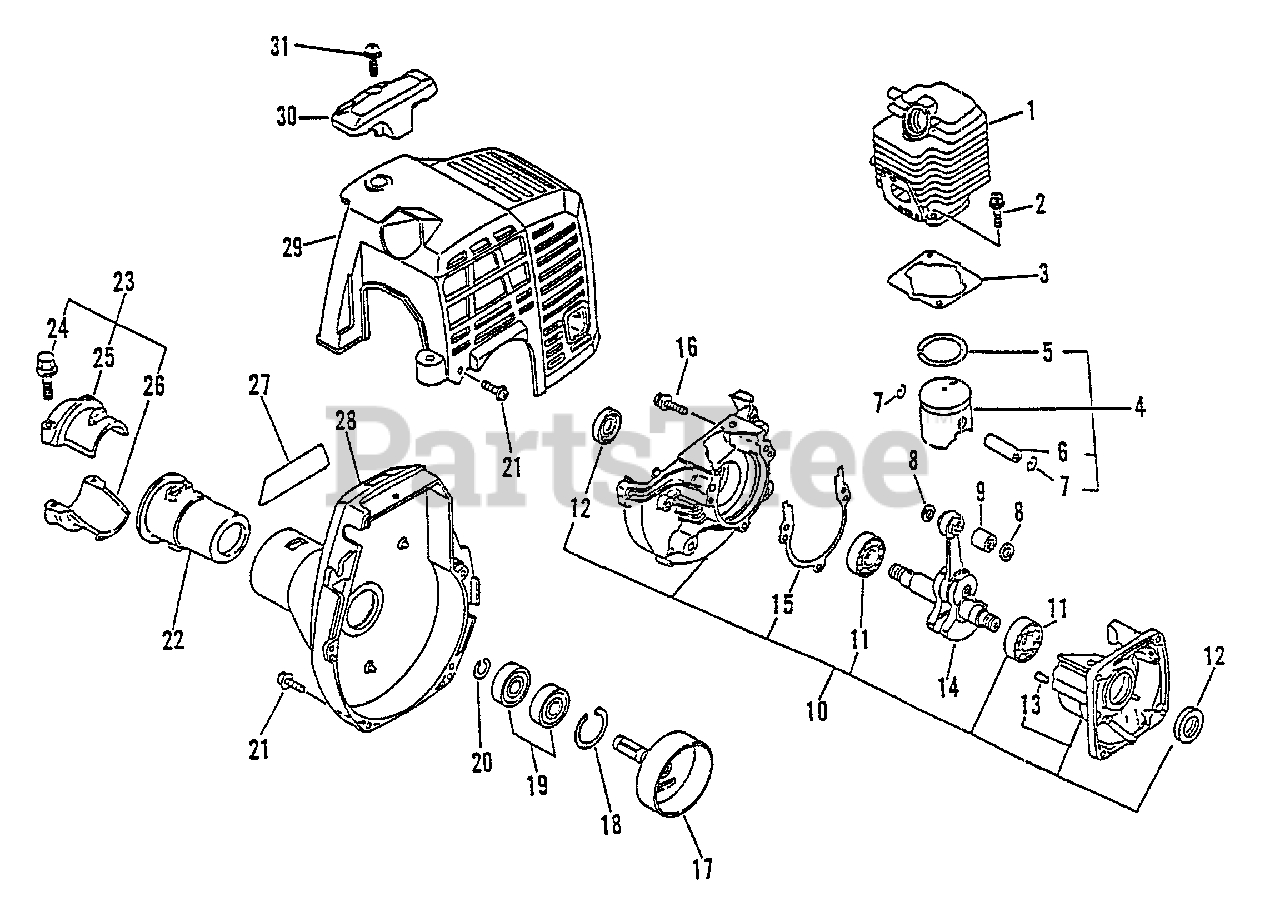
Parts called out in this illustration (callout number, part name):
1	CYLINDER
2	SCREW - 5X22
3	GASKET, CYLINDER
4	PISTON KIT
5	RING, PISTON
6	PIN, PISTON
7	RING, RETAINING
8	SPACER, PISTON
9	BEARING, NEEDLE
10	CRANKCASE KIT
11	BEARING, BALL - 6201
12	SEAL, OIL
13	PIN - LOCATING
14	CRANKSHAFT ASSY
15	GASKET, CRANKCASE
16	SCREW - 5X28
17	DRUM, CLUTCH
18	RING, RETAINING - 28
19	BEARING, BALL - 6001
20	RING, RETAINING - 12
21	SCREW - 4X16
23	HOLDER KIT
24	BOLT - 5X25
25	CLAMP, MAIN PIPE - UPPER
26	CLAMP, MAIN PIPE
27	LABEL - MODEL LST-2100
28	FAN CASE ASSY
29	COVER, ENGINE
30	GUARD - TOP
31	SCREW - 5X16
31	SHORT BLOCK -- SB1007
31	GASKET KIT
31	GASKET, CYLINDER
31	GASKET, CRANKCASE
31	GASKET, INTAKE
31	SHIELD, INTAKE
31	GASKET, EXHAUST
